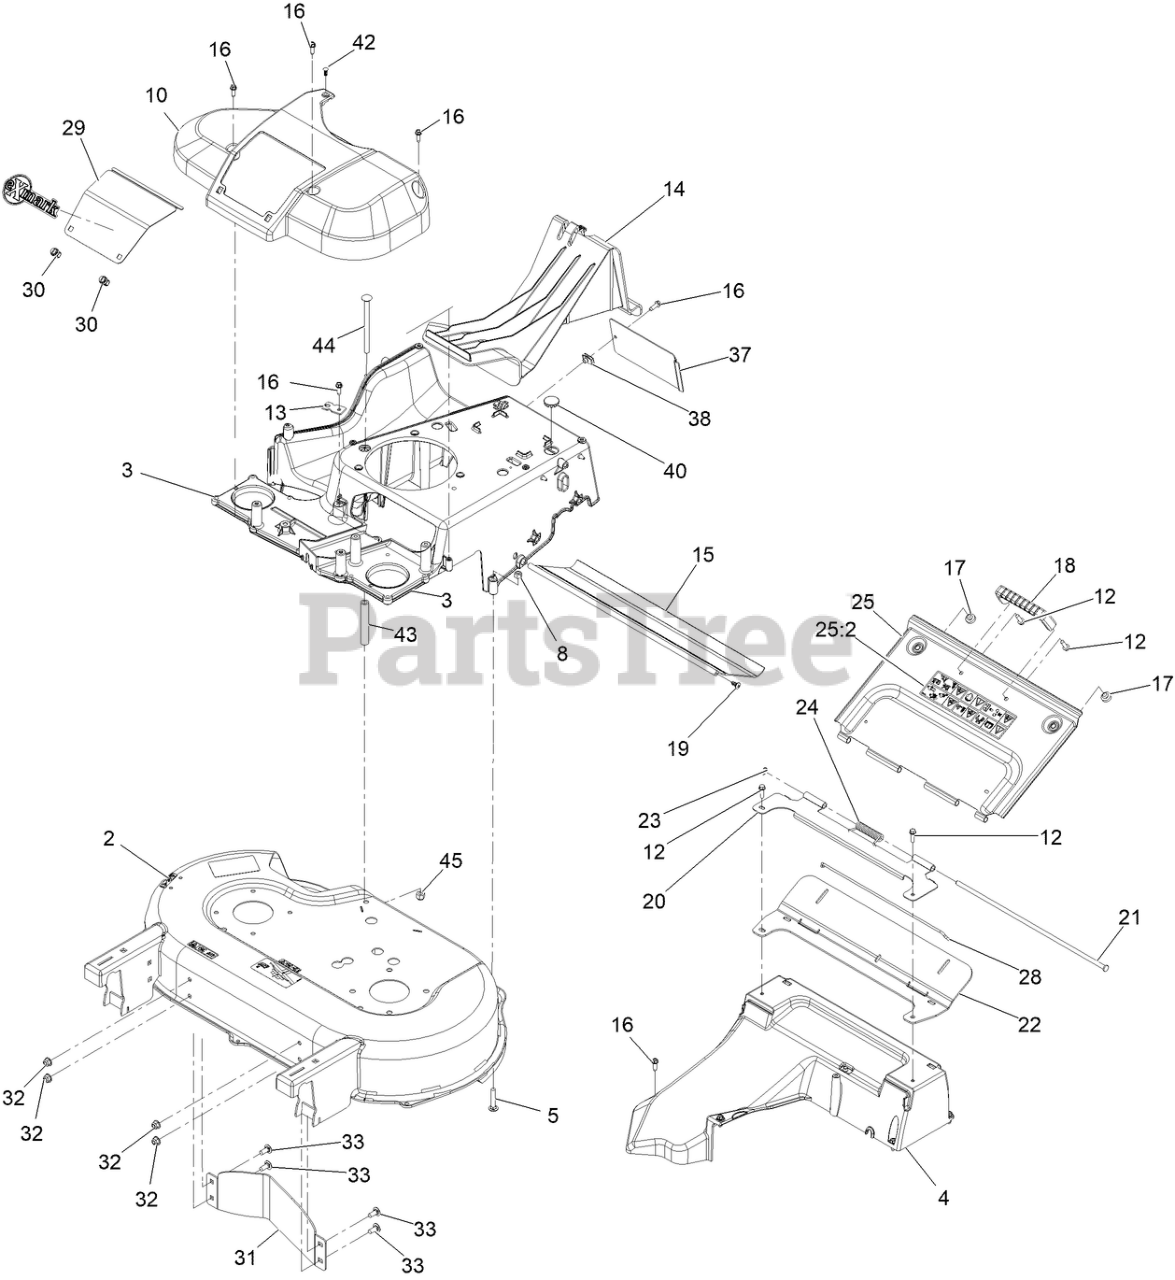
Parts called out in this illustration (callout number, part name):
2	DECK-30, X-SERIES W/DECALS
5	BOLT-CAR
8	NUT-LOCK, NI
10	COVER-BELT
12	SCREW-HWH
13	BRACKET-CABLE, TRACTION
14	PLUG-MULCH
15	SHIELD-TRAILING
16	SCREW-HWHTF
18	HANDLE-DOOR
19	SCREW-PTH
20	Weld-Tank Mount
21	PIN-HINGE
22	SEAL-DOOR
23	RING-RETAINING
24	SPRING-TORSION, COVER
25	REAR DOOR ASM
25:2	DECAL-WARNING
28	CLIP-SEAL
29	DOOR-ACCESS
30	FASTENER
31	BAFFLE-CONTROL
32	NUT-HF, NI
33	SCREW-HSBH
37	Cover-Frame
40	PLUG-BUTTON
42	Clip-Xmas Tree
44	BOLT-CARR
45	NUT-HEX
